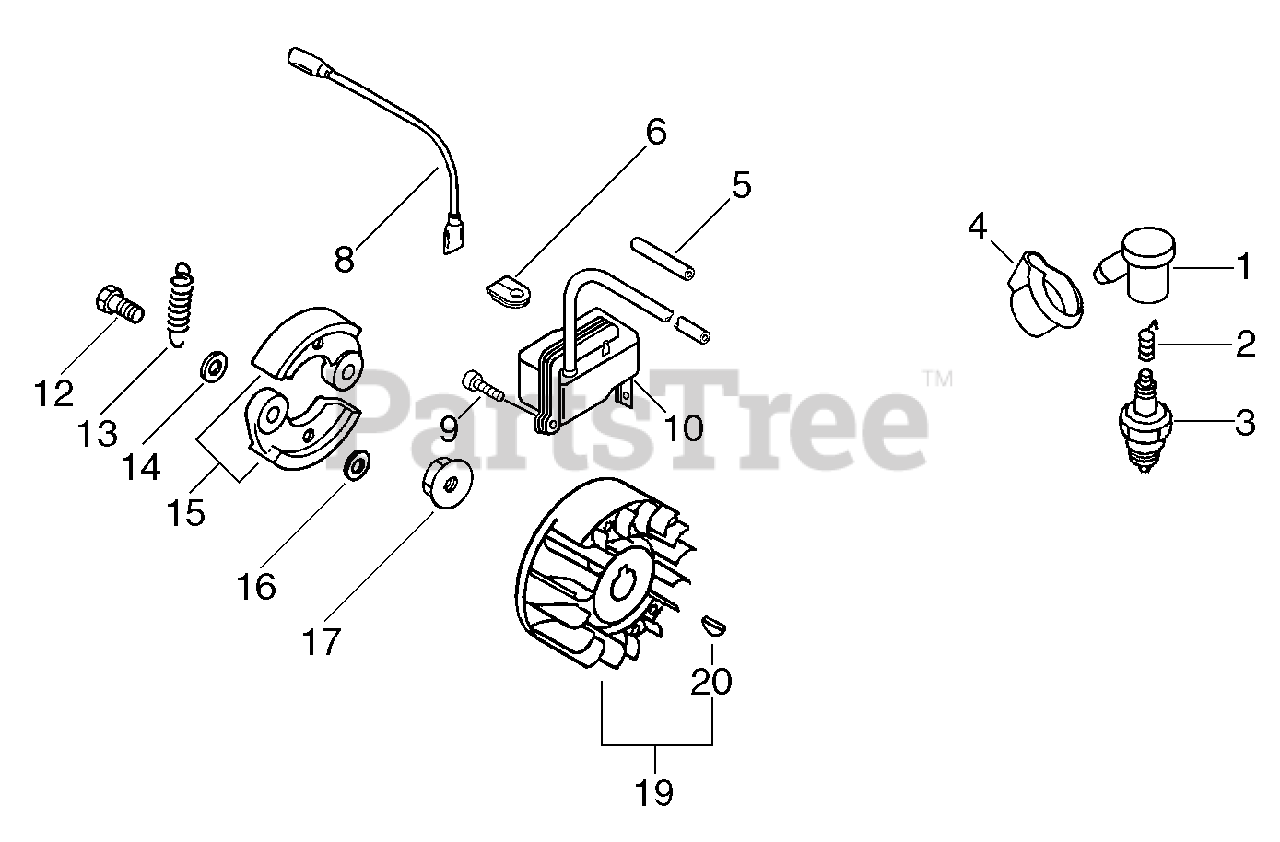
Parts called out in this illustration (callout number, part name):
1	CAP, SPARK PLUG
2	TERMINAL, SPARK PLUG CAP
3	SPARK PLUG -- BPM-7A
4	COVER, DUST
5	TUBE, INSULATOR
8	LEAD - IGNITION
9	SCREW - 5X20
10	COIL, IGNITION
12	BOLT, CLUTCH
13	SPRING, CLUTCH
15	CLUTCH SHOE SET
17	NUT - 10 -- FLANGE
19	FLYWHEEL KIT
20	KEY - 3X14
